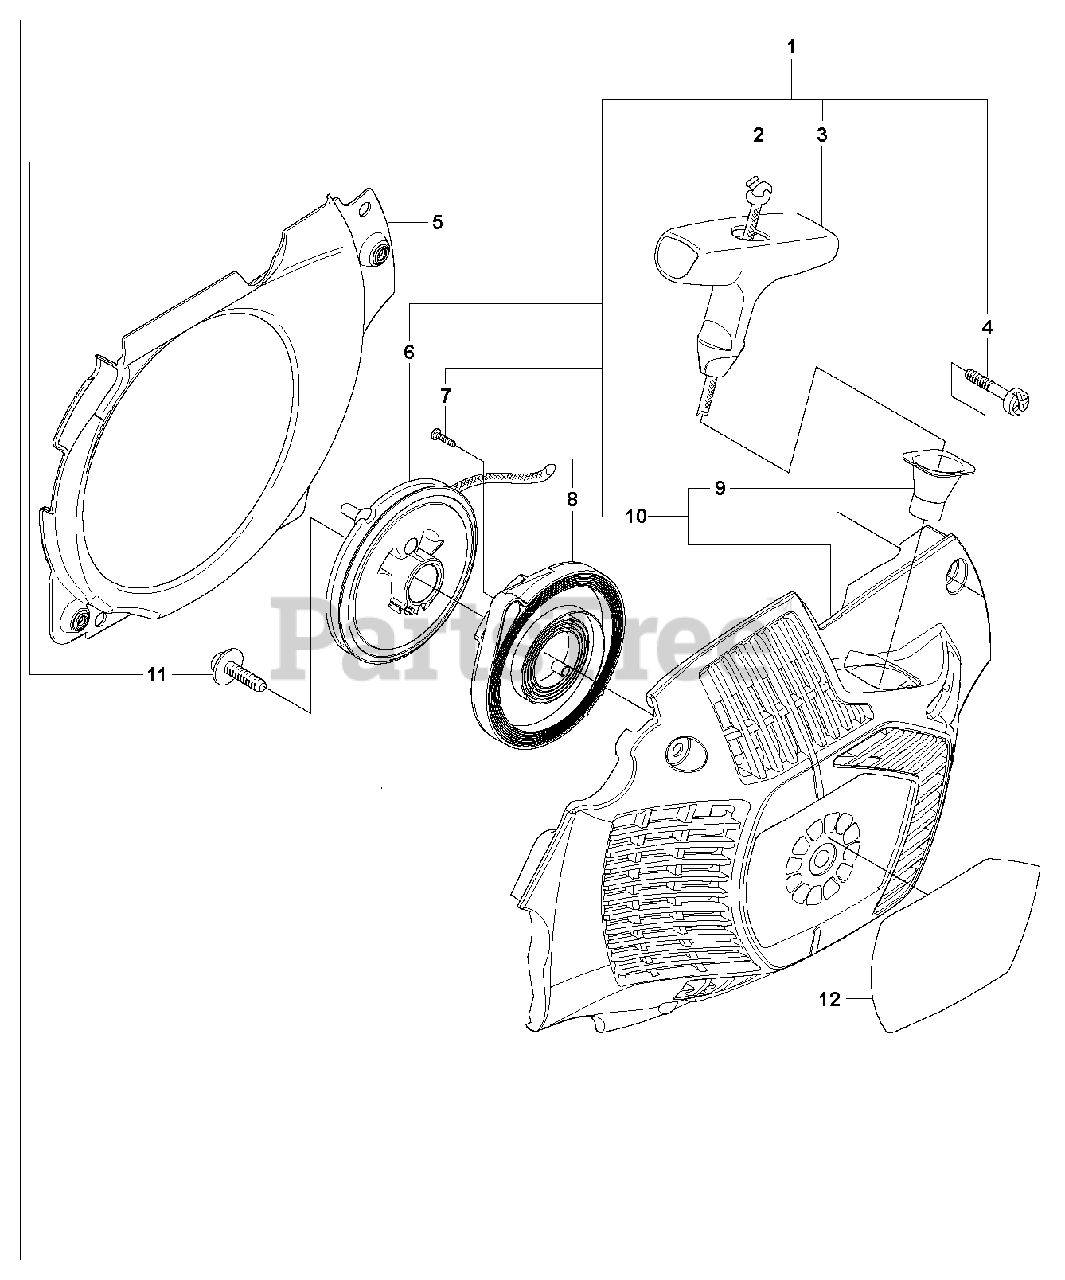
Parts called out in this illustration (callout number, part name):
1	STARTER ASSY
2	STARTER ROPE
3	HANDLE
4	SCREW
5	PLATE
6	STARTER PULLEY
7	SCREW
8	RP SPRING
9	SLEEVE
10	STARTER HOUSING
11	SCREW
12	DECAL
